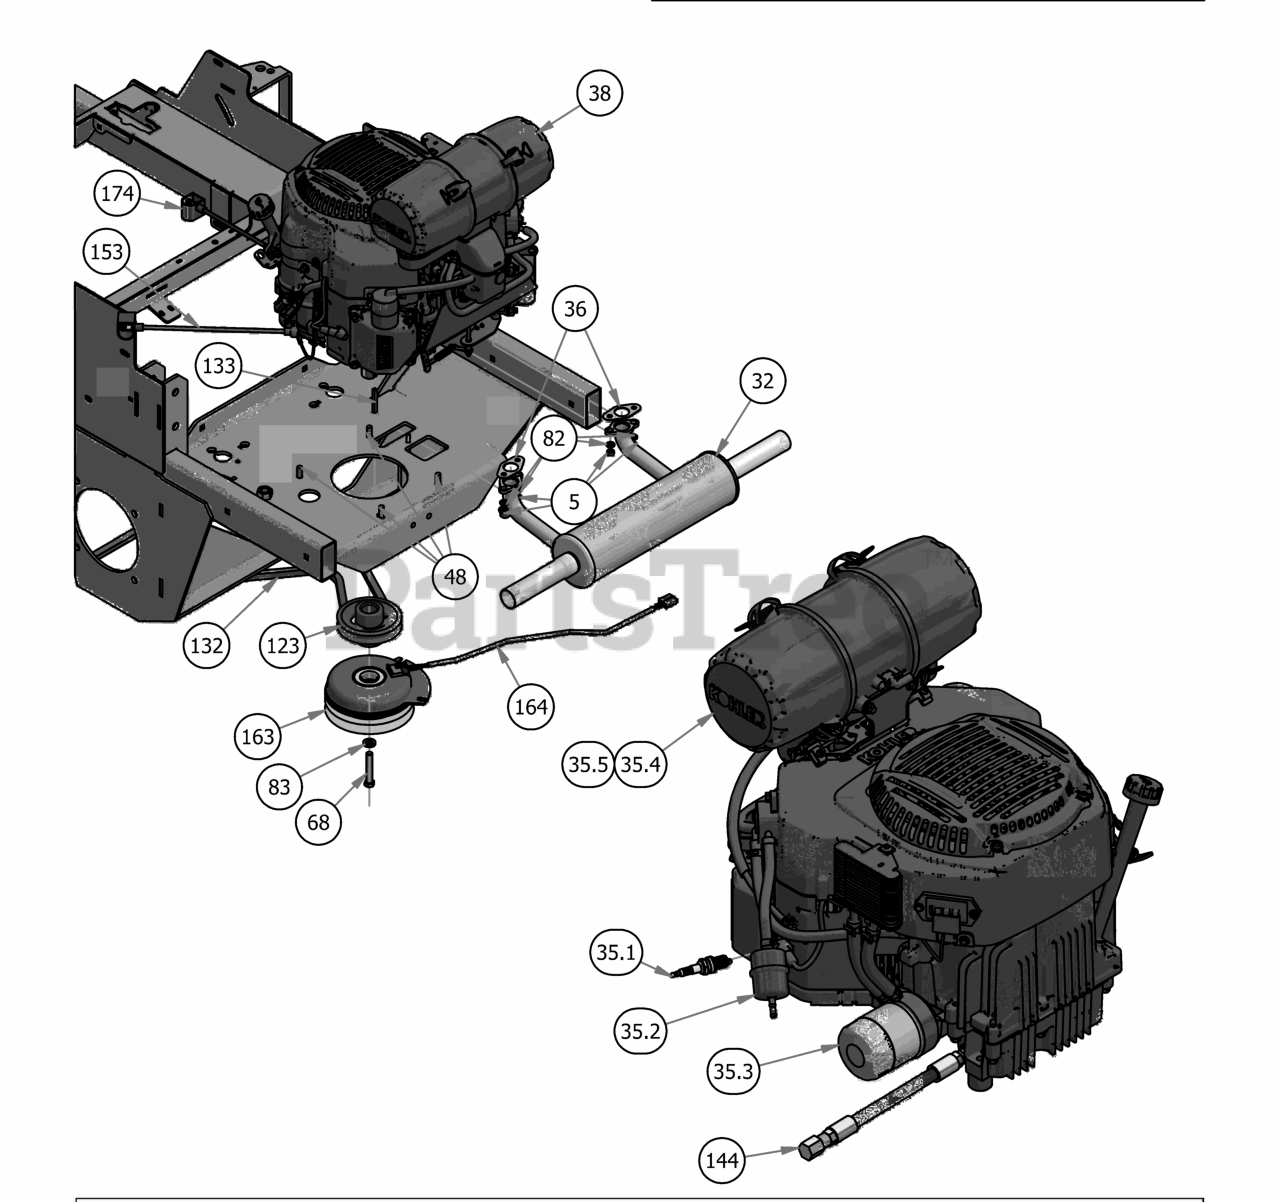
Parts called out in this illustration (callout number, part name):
5	M8-1.25 Zinc Nut
32	2019 Rebel Kohler CV752 Muffler
35.1	Spark Plug
35.2	25/26 HP Kohler Fuel Filter
35.3	Oil Filter
35.4	Canister Air Filter- Outer
35.5	Canister Air Filter- Inner
36	Exhaust Gasket
38	Kohler Command Engine
48	3/8 x 1 1/8 bolt
68	7/16" x 2 1/2" Hex Bolt
82	5/16" Lock Washer
83	7/16" Lock Washer
123	4 3/4 Motor Pulley
132	2019 Rebel Pump Belt
133	1/4 x 2 Square key Stock
144	Oil drain Hose for Yamaha
153	14" Red Battery Cable-Base Outlaw
163	Clutch Assembly
164	Clutch Pigtail
165	2019 Rigid Frame
174	Starter Cable
